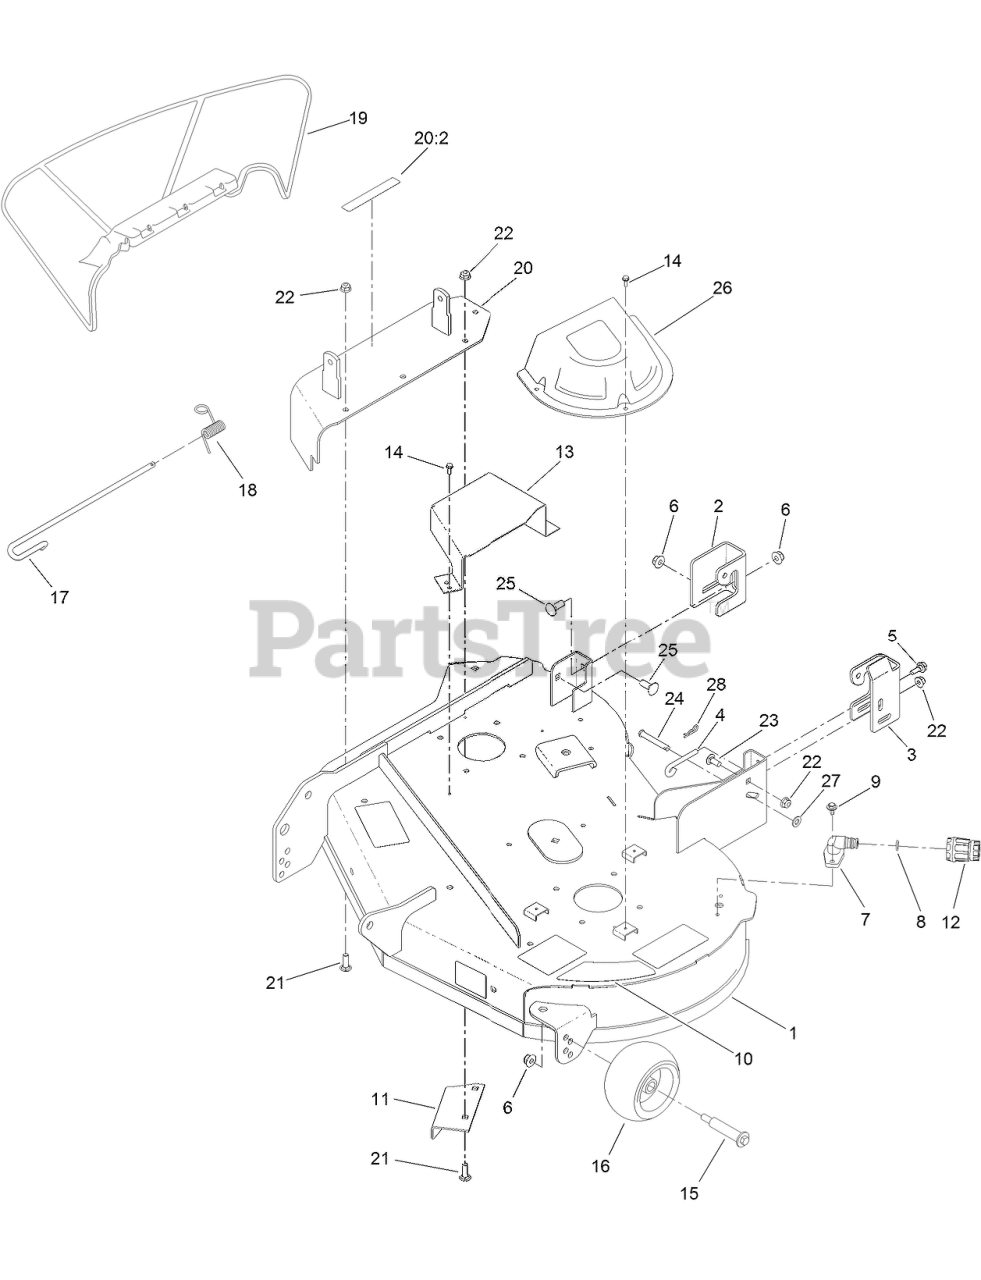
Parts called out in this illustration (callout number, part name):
1	34 INCH DECK AND DECAL ASM
2	BRACKET-HANGER, RH
3	BRACKET-HANGER, LH
4	ROD-LEVEL, DECK
6	NUT-HF, NI
7	FITTING-WASHOUT
8	O-RING
9	SCREW-HHFTF
10	DECAL-DECK
11	BAFFLE-CUTOFF
12	CONNECTOR-HOSE
13	COVER-DECK BELT
14	SCREW-TAPTITE
15	BOLT-SHOULDER
16	ROLLER-SCALP, ANTI
17	PIN-CHUTE
18	SPRING-TORSION
19	DEFLECTOR-DISCHARGE
20	COVER ASM W/DECAL
20:2	DECAL-DANGER
21	SCREW-CARR
22	NUT-HF, NI
23	SCREW-CARR
24	PIN-CLEVIS
26	COVER-BELT
27	WASHER-PLAIN
28	PIN-COTTER
